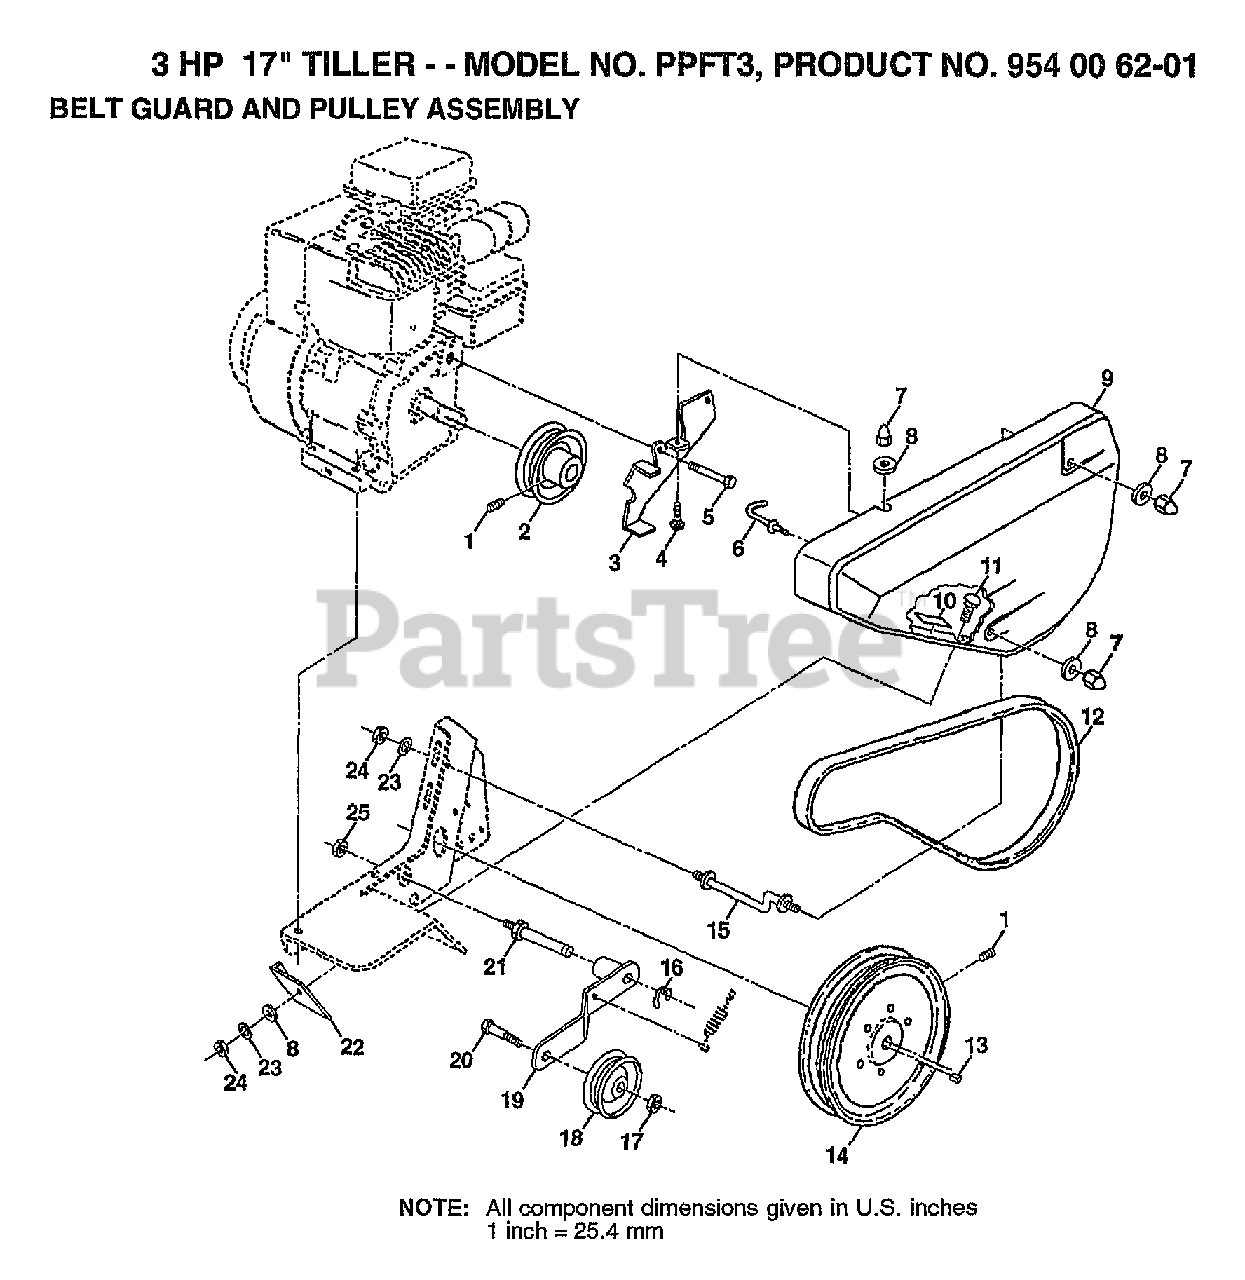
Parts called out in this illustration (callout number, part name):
1	SCREW, SET FORGED SOCKET, HEADLESS 5/16-18X3/8
2	ENGINE PULLEY
4	BOLT, CARRIAGE 1/4-20X3/4
5	BOLT, HEX 1/2-20X3/4
8	WASHER 9/32 X 5/8 X 16 GA.
11	BOLT, CARRIAGE 1/4-20 X 3/4
15	BELT GUARD BOLT
17	NUT HEX JAM 3/8-16 UNC
20	BOLT, HEX 3/8-16 X 1-1/4
23	WASHER, LOCK 1/4
24	NUT, HEX 1/4-20
25	NUT, HEX, JAM 5/16-18
